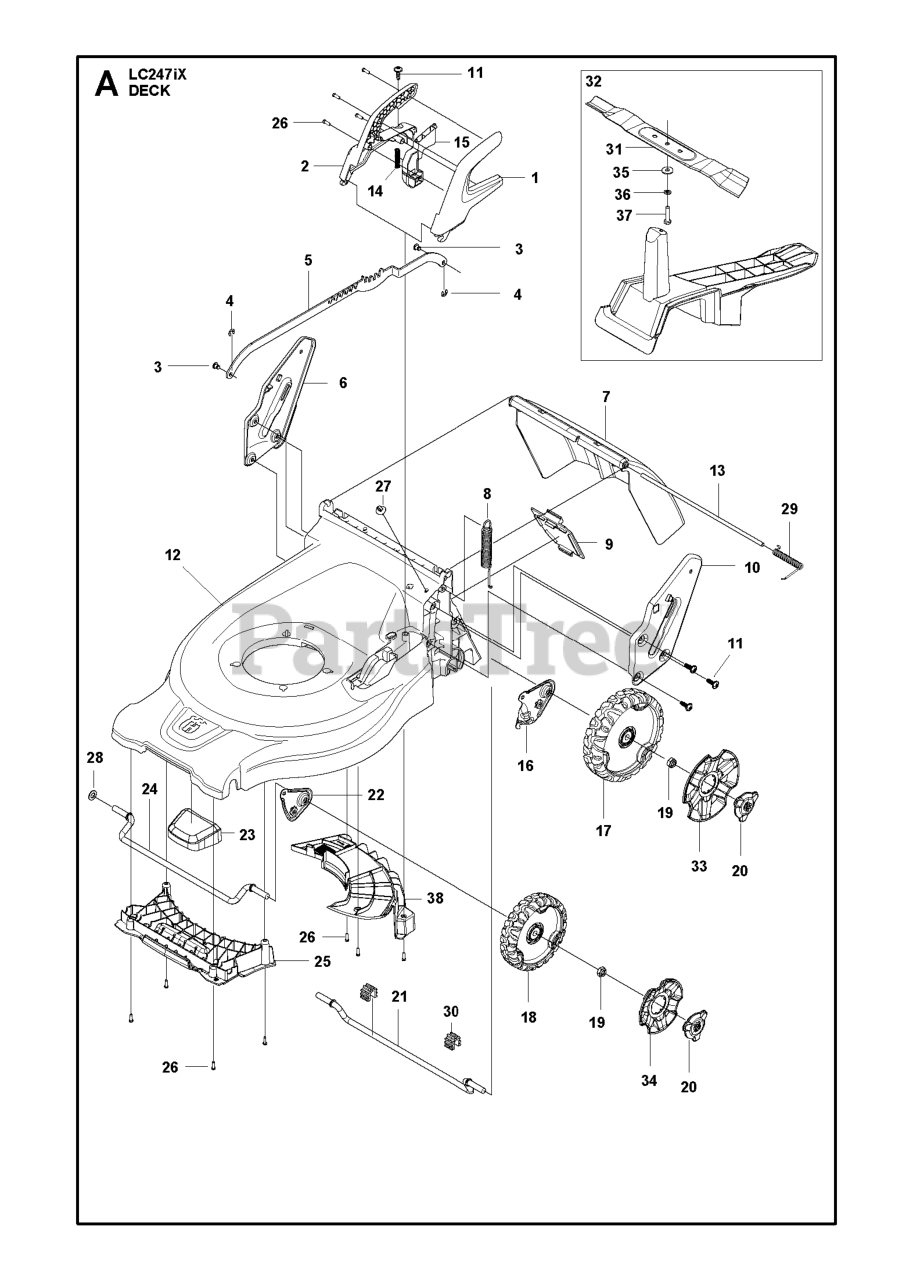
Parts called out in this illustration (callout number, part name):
4	Retaining Ring
20	NUT CAP
26	SCREW ITXPANT T50X16 ZN/FE (A
28	Washers
33	HUB CAP
35	SPACER
36	SPRING WASHER
37	SCREW
